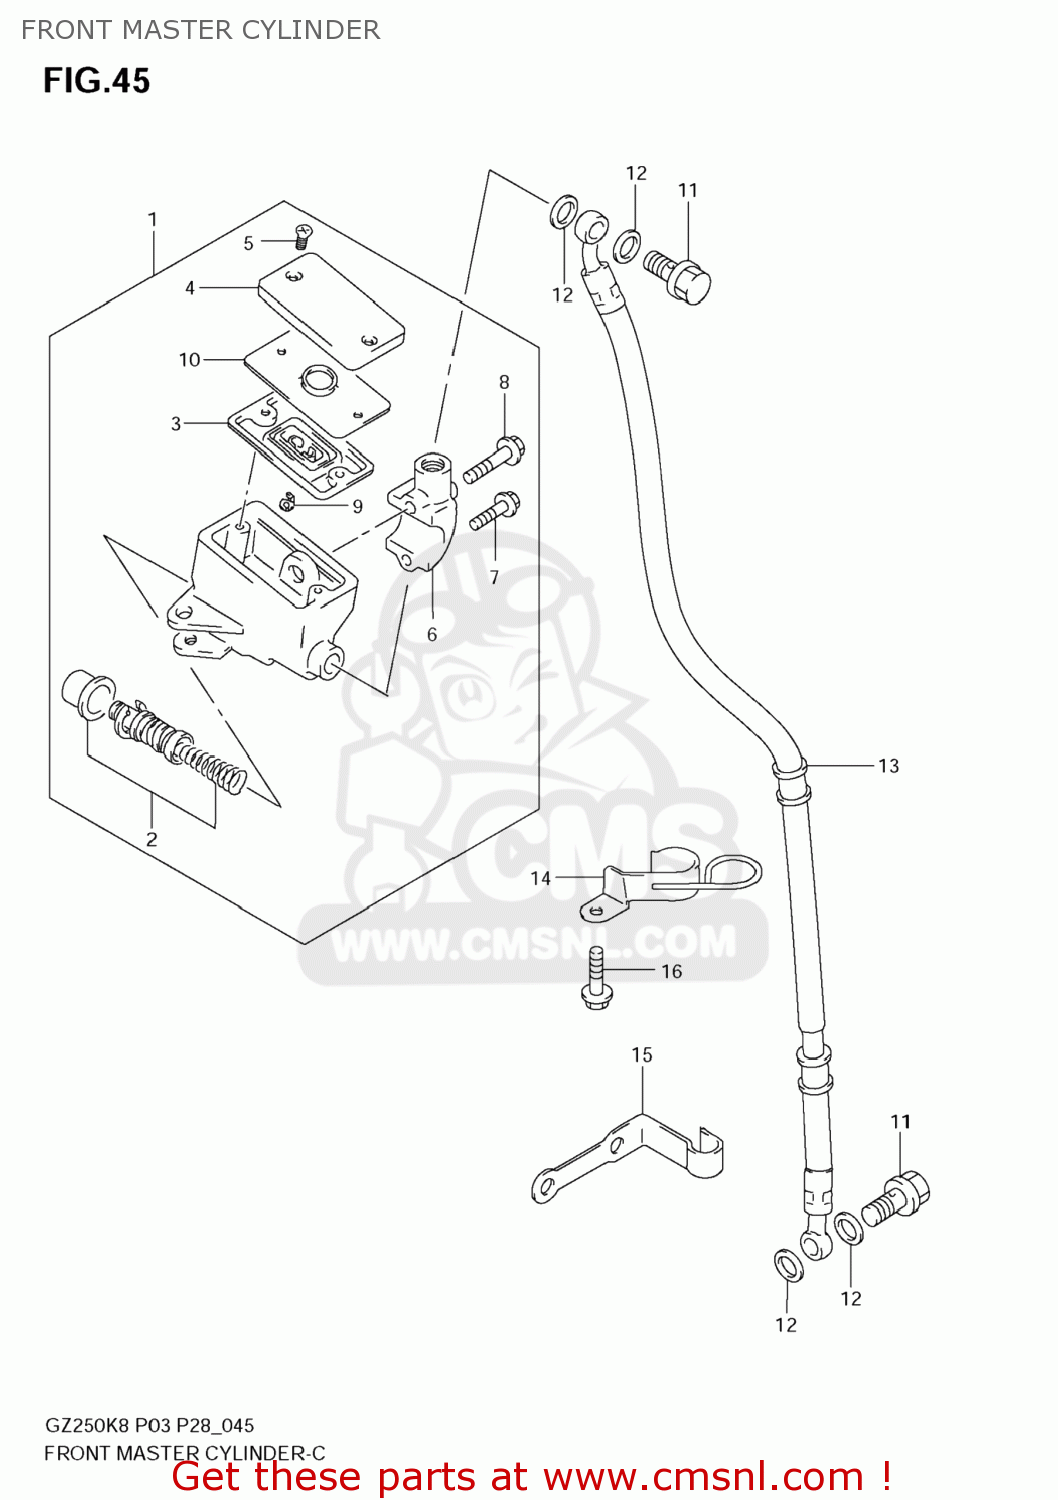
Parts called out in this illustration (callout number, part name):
1	CYLINDER ASSY
2	PISTON/CUP SET
3	DIAPHRAGM
4	CAP
5	SCREW
6	HOLDER
7	BOLT
8	BOLT UPPER
9	PROTECTOR
10	PLATE
11	BOLT UNION
12	WASHER(10X15X1.5)
13	HOSE,FRONT BRAK
14	CLAMP,FR BRAKE HOSE
15	CLAMP,BRAKE HOSE
16	BOLT
